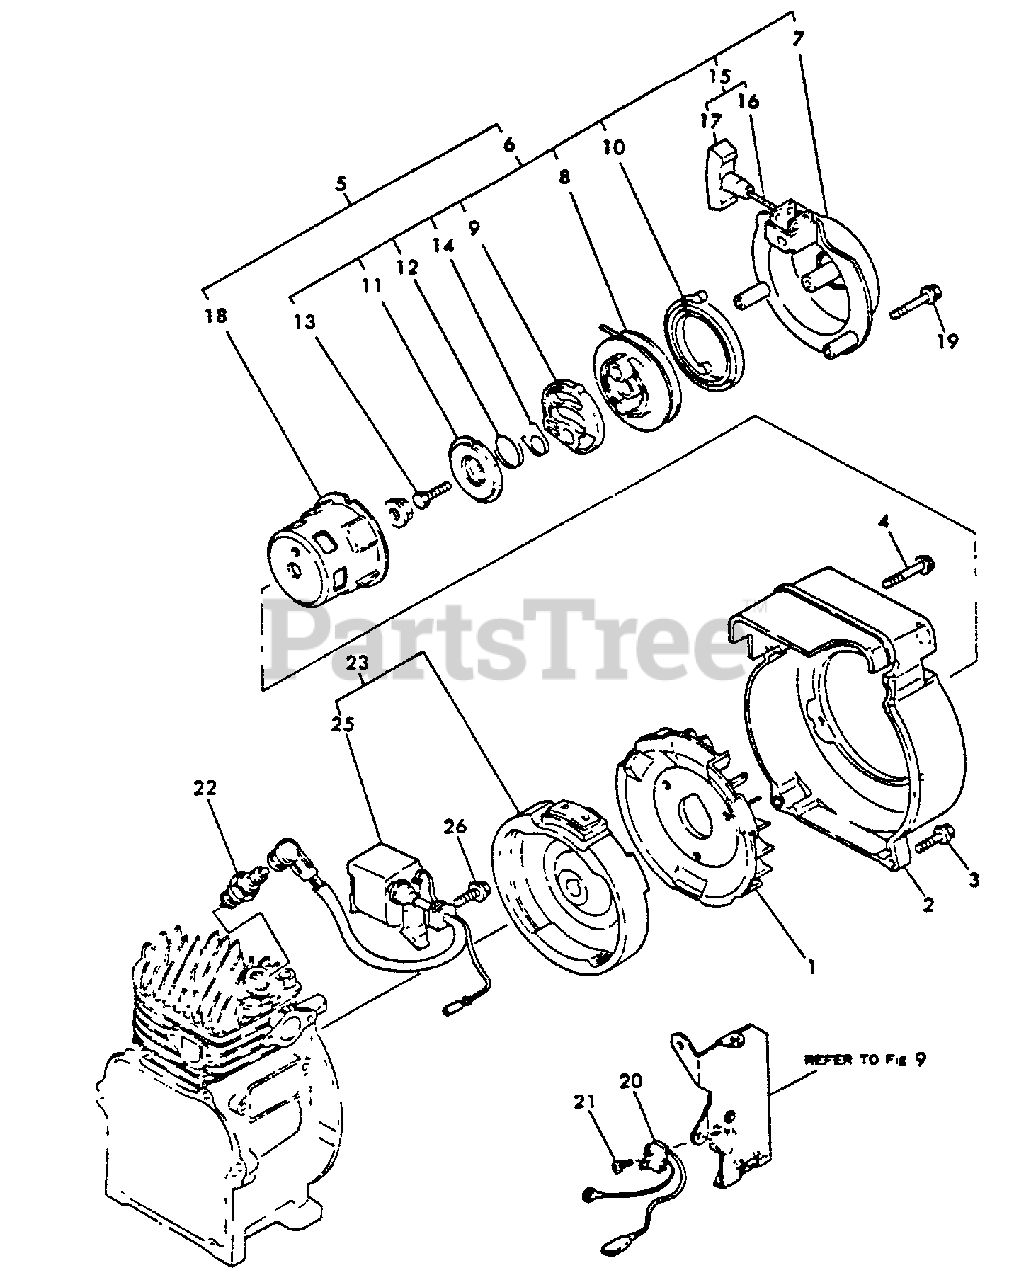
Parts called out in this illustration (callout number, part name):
1	FAN
2	COVER, FAN
3	BOLT - 6X25
4	BOLT - 6X30
5	STARTER ASSY
6	STARTER ASSY
7	STARTER CASE ASSY
8	PULLEY
9	RATCHET
10	SPRING
11	PLATE, FRICTION
12	SPRING, FRICTION
13	BOLT
14	SPRING, RETURN
15	STARTER ROPE ASSY
16	ROPE, STARTER
17	KNOB, STARTER
18	PULLEY, STARTER
19	BOLT - 6X35 -- PLATED
20	IGNITION SWITCH ASSY
21	SCREW - 2X10 -- TAPPING
22	SPARK PLUG -- BPM-8Y
23	FLYWHEEL MAGNETO ASSY
25	COIL, IGNITION
26	BOLT - 6X25
